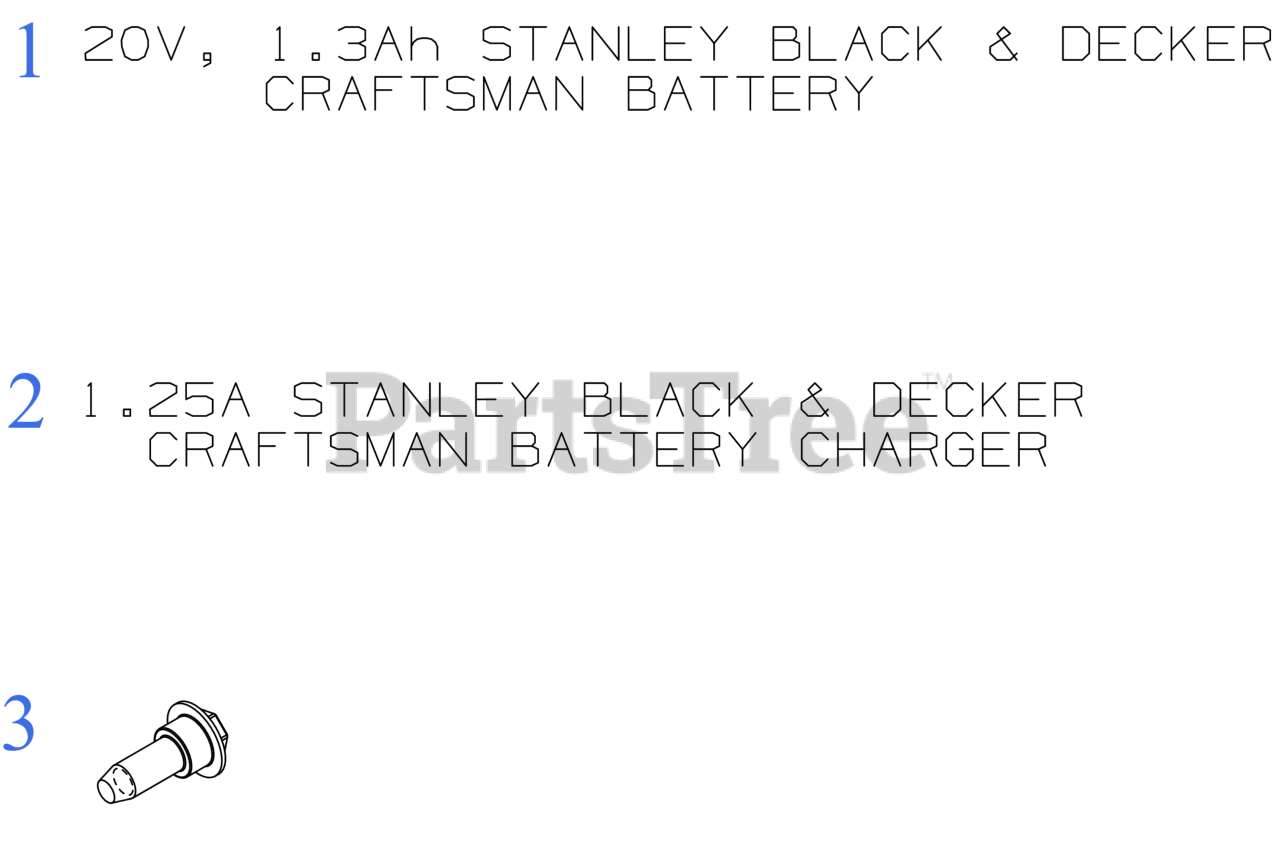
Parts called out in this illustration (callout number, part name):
1	BATTERY LI-ION 20V 1.3AH (CRAFTSMAN SBD)
2	CHARGER 1.25V (CRAFTSMAN SBD)
3	SHOULDER SCREW 5/16-14 x .972
